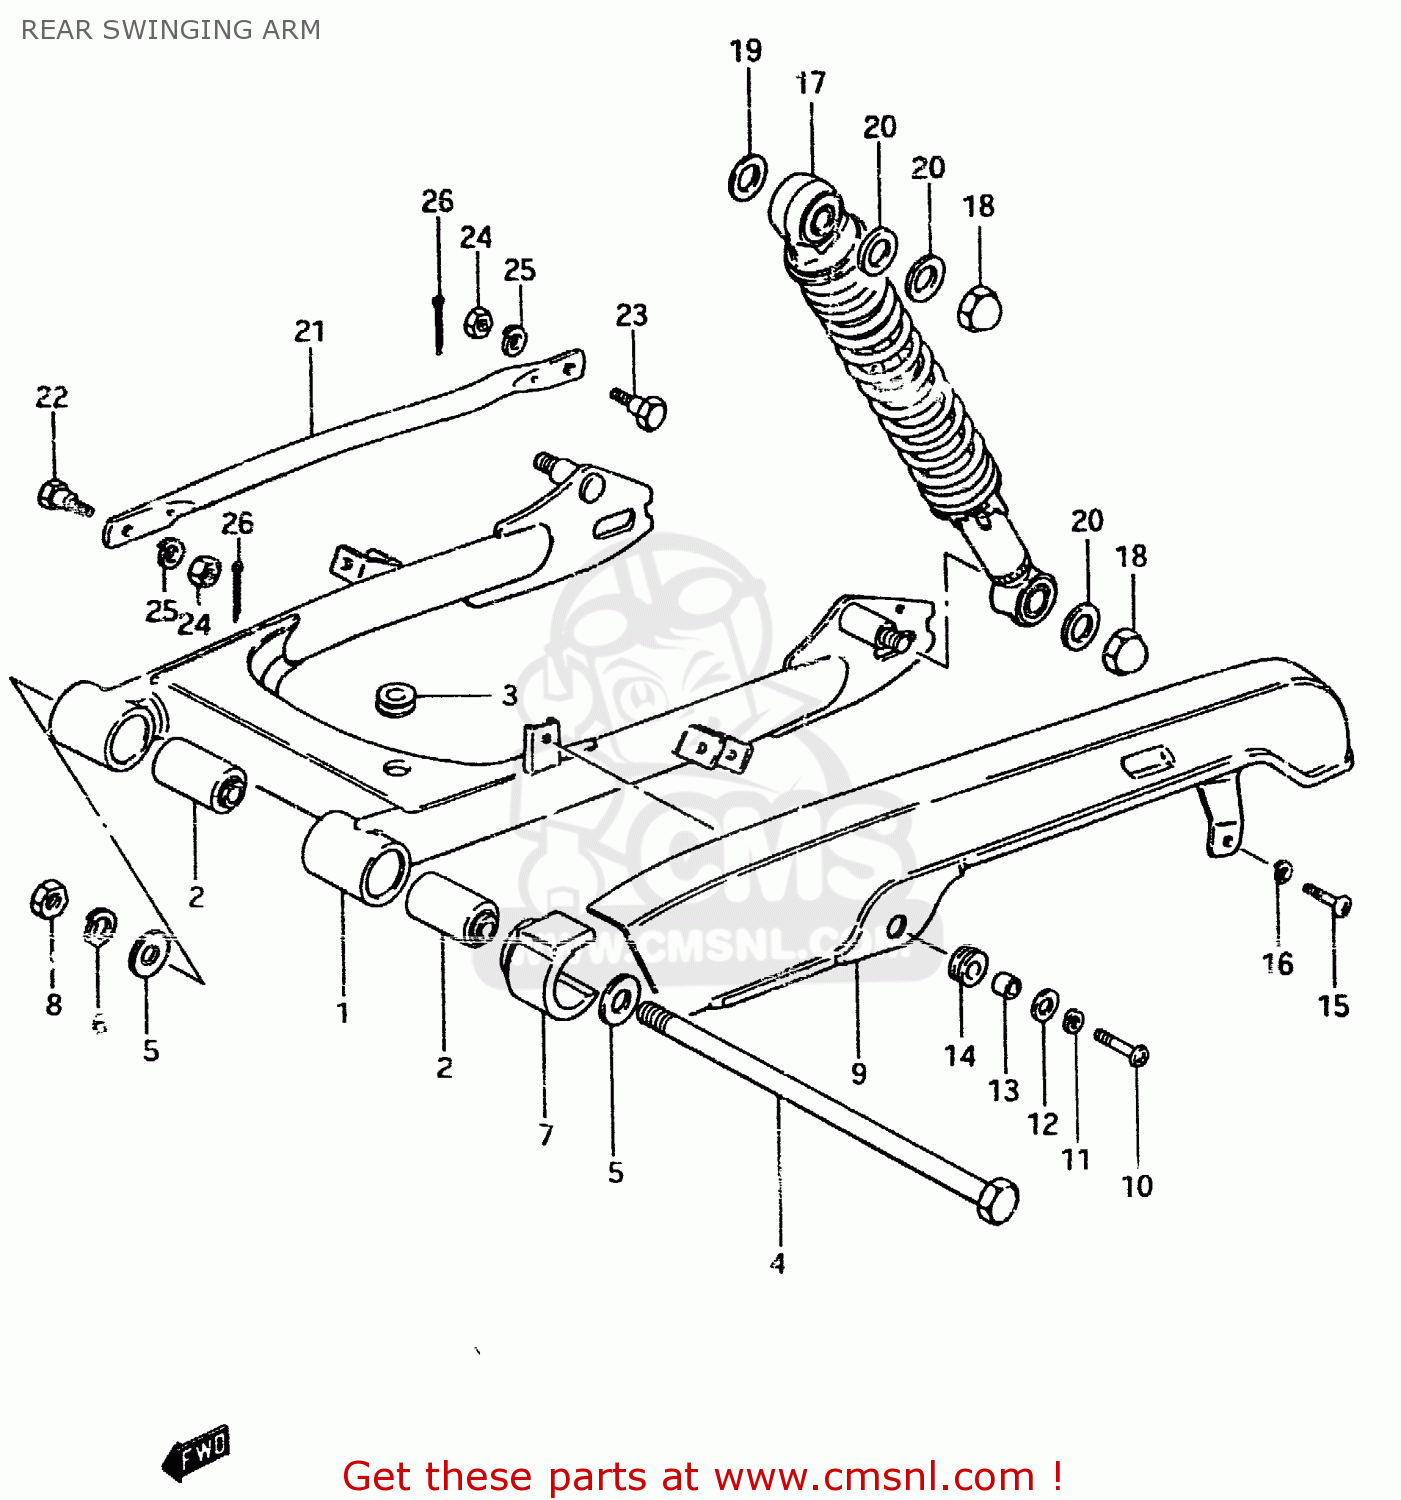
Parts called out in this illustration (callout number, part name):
1	SWINGING ARM SET, REAR
2	BUSH
3	CUSHION
4	SHAFT,RR SHOCK ABSORBER UPR
5	WASHER
6	LOCK WASHER
7	BUFFER,CHAIN TOUCH DEFENSE
8	NUT
9	CHAIN CASE
10	SCREW
11	LOCK WASHER
12	WASHER (6.5X20X1.2)
13	SPACER (7X9X7)
14	CUSHION
15	SCREW 6X12
16	LOCK WASHER
17	SHOCK ABSORBER, REAR
18	NUT, LOWER LH
19	WASHER
20	WASHER
21	TORQUE LINK, REAR
22	BOLT(8X22)
23	BOLT(8X26.5)
24	NUT
25	LOCK WASHER
26	PIN 20X20
